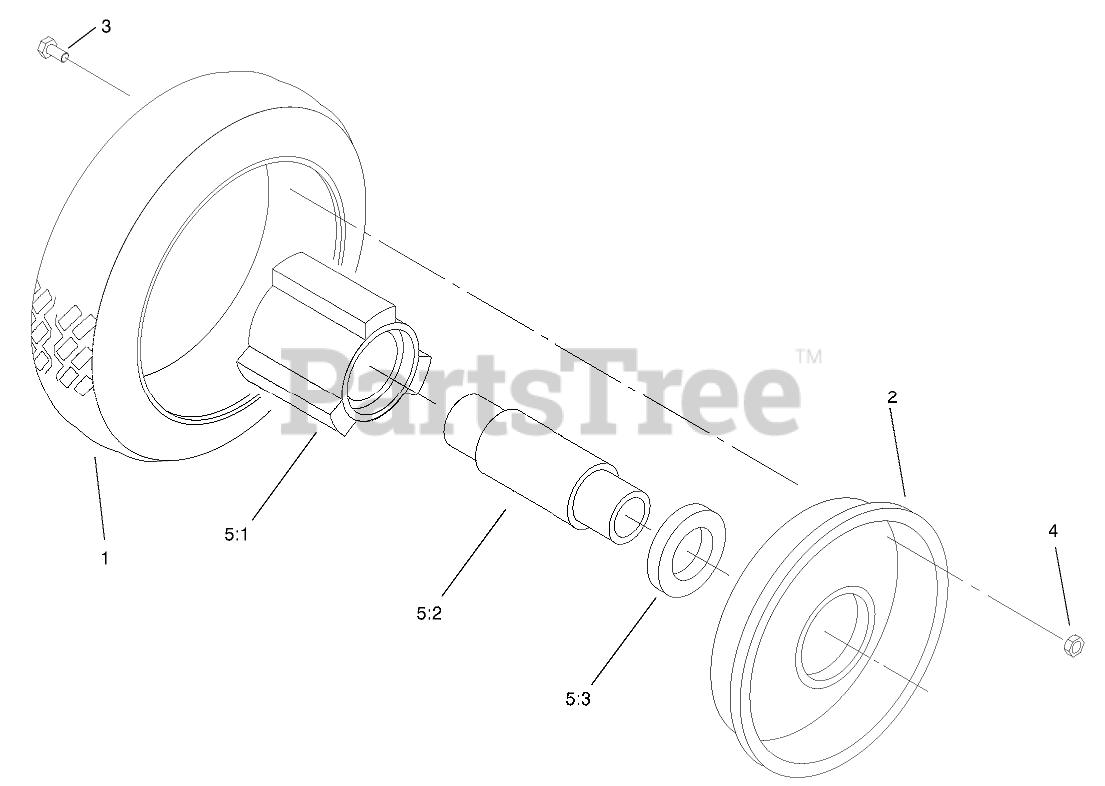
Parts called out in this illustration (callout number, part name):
2	PLATE-WHEEL, HALF
3	SCREW-HH
4	NUT-LOCK, NI
5	HUB and BEARING ASM
5:1	HUB-BEARING
5:2	SPACER-BEARING
5:3	BEARING-WHEEL
